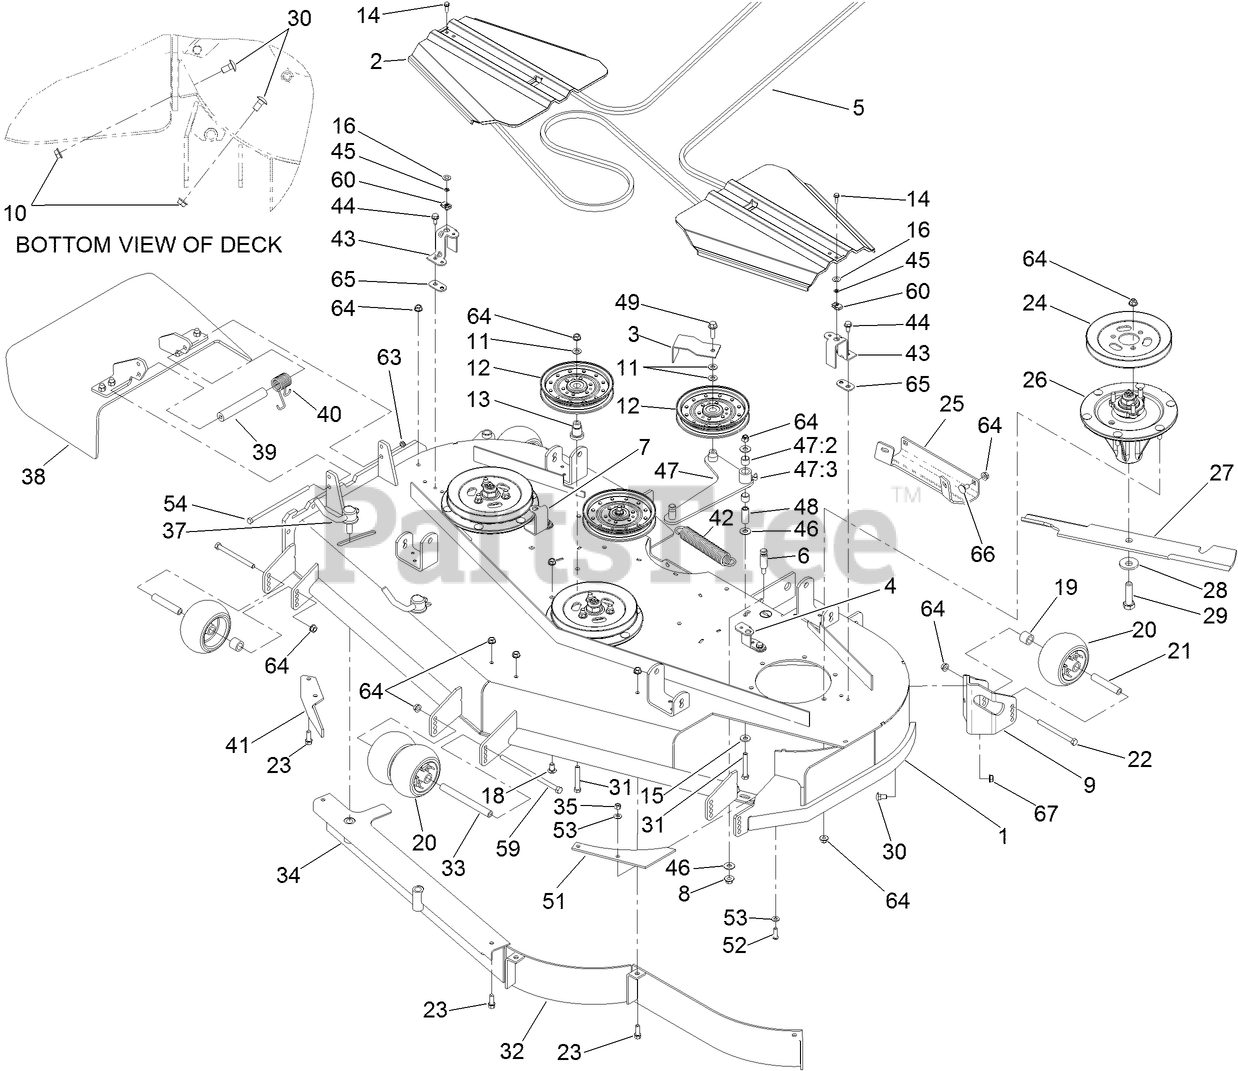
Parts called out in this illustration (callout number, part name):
2	COVER-BELT
3	GUIDE-BELT
4	BRACKET-COVER, TALL
5	BELT-V
6	PIN-THREADED, SPRING ANCHOR
7	BRACKET-COVER
8	NUT-HF
9	MOUNT-WHEEL, LH
10	NUT-HHF, WHIZ
11	WASHER-FLAT
13	MOUNT-PULLEY
14	SCREW-HWH
15	WASHER-BELLEVILLE
16	WASHER-THRUST
18	SCREW-CARR
19	TUBE-SPACER
20	ROLLER-SCALP, ANTI
21	TUBE-SPANNER
22	SCREW-HH
24	PULLEY
25	PLATE-SKID
26	SPINDLE ASM
27	BLADE-HI FLOW
28	WASHER-BLADE BOLT, HEAVY
29	SCREW-BLADE
30	SCREW-HH
31	SCREW-HH
33	SPACER-WHEEL
35	NUT-LOCK, NI
37	LEVER ASM
38	RUBBER DEFLECTOR ASM
39	SPACER
40	SPRING-TORSION
41	BAFFLE-DISCHARGE
42	SPRING-EXTENSION
43	BRACKET-COVER
44	SCREW-HWHTF
45	NUT-RETAINER
46	WASHER-FLAT
47	DECK IDLER ARM ASM
47:2	SLEEVE-BEARING
47:3	FITTING-GREASE, 90 DEG
48	BUSHING
49	SCREW-HHF
51	PLATE-TURBO
52	SCREW-HSBH
53	WASHER-SPRING
54	SCREW-HH
59	SCREW-HH
63	NUT-LOCK, NI
64	NUT-HF, NI
65	SPACER-BELT COVER
66	SCREW-CARR
